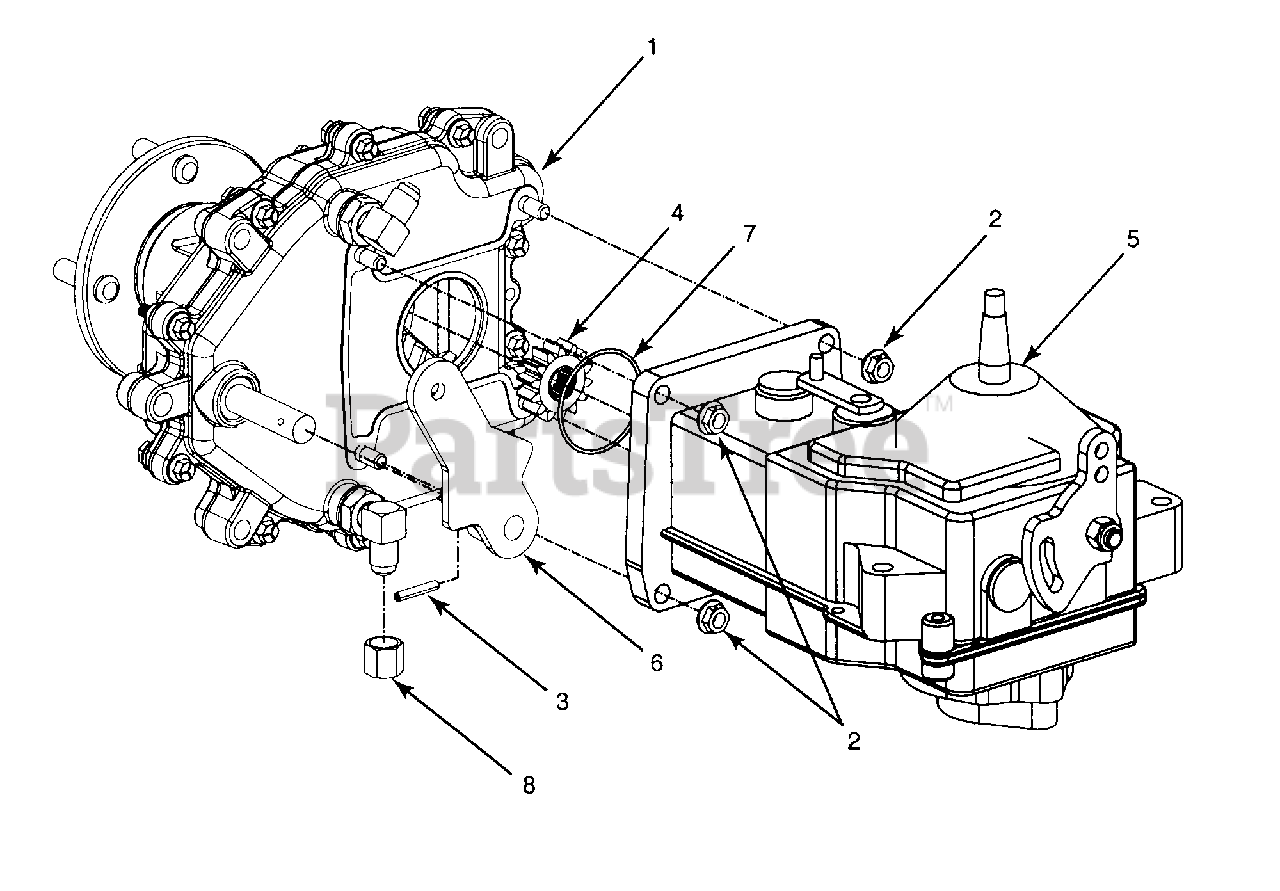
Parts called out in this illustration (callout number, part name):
1	Drive Ass'y Complete
2	Hex Flange Lock Nut 5/16-18
3	Spirol Pin 3/16 x 1.25
4	Spur Gear 14T
5	Hydro Transmission
6	Parking Brake Lever
7	O-Ring 2.0 Dia.
8	Cap Nut 3/8
